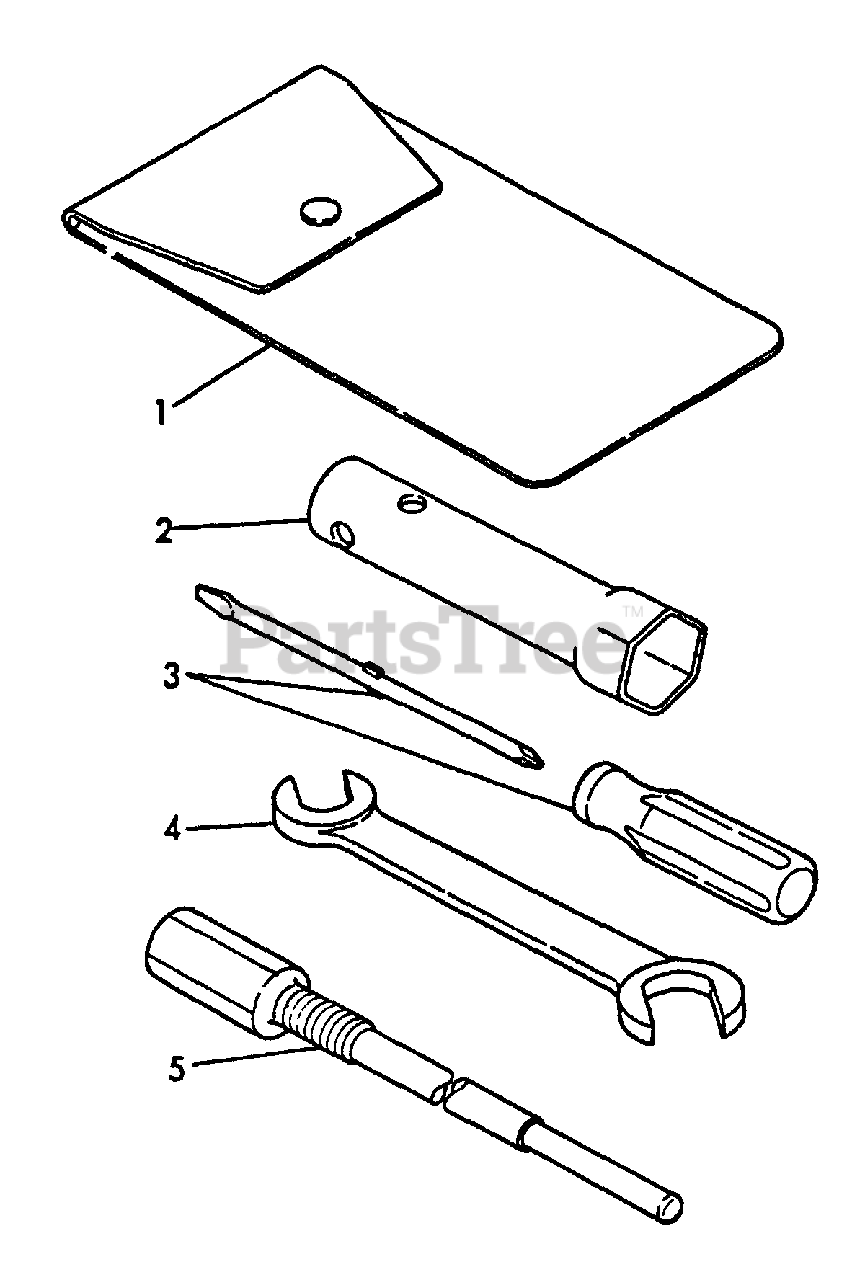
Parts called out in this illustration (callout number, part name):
1	BAG, TOOL
2	BOX SPANNER - 21
3	SCREWDRIVER
4	WRENCH 10×12
5	TOOL, ROTOR REMOVAL
